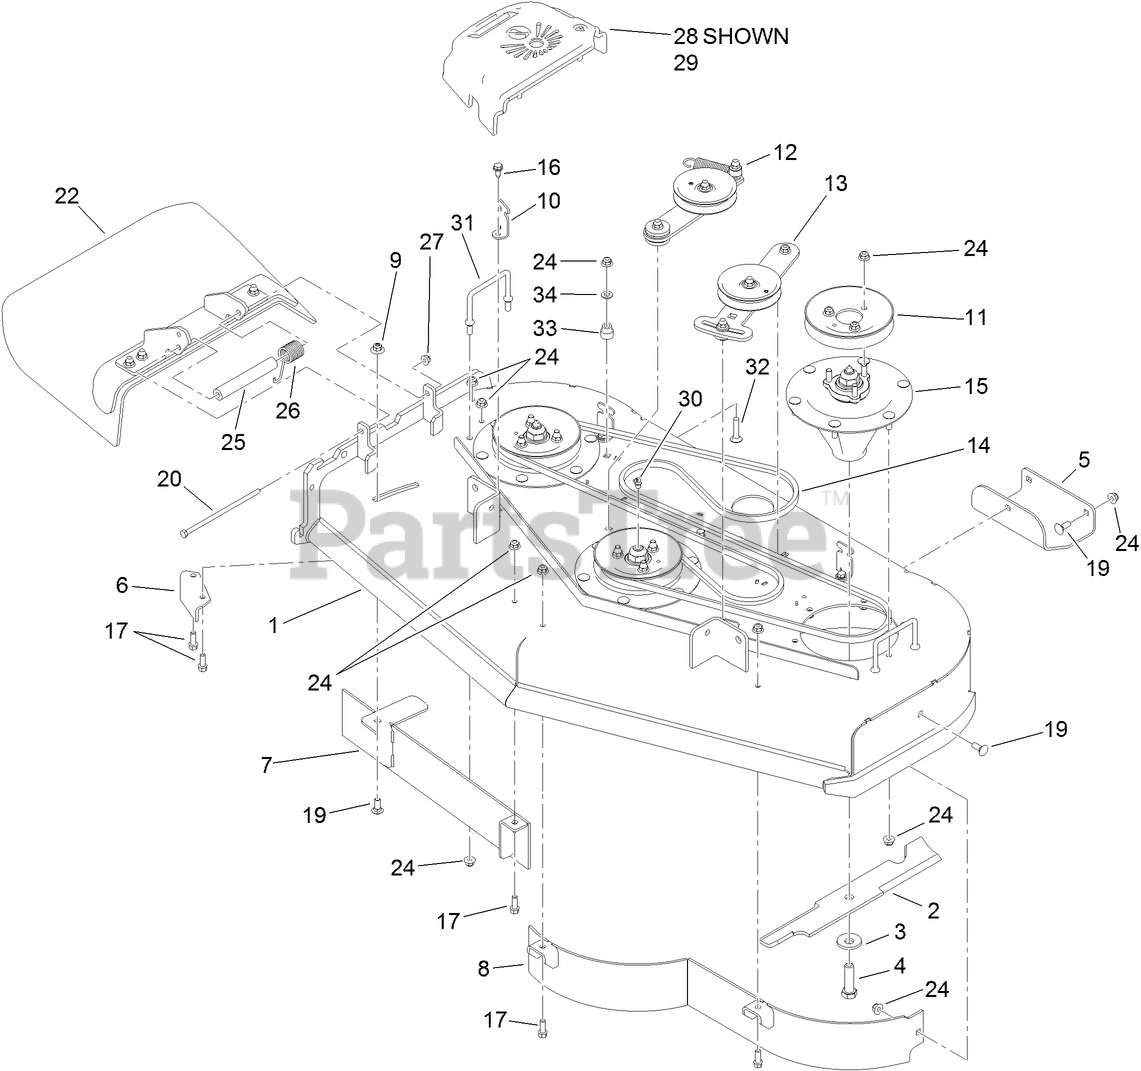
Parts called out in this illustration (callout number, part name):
1	DECK ASM
2	BLADE-16.5 INCH (HIGH FLOW)
3	Washer-Blade Bolt, Heavy
4	SCREW-BLADE
6	BAFFLE-DISCHARGE
8	48 INCH BAFFLE ASM
9	NUT-FLANGE, NI
10	BRACKET-COVER
11	PULLEY
12	IDLER ARM ASM
13	IDLER ADJUST ASM
14	BELT-V
15	SPINDLE ASM
16	SCREW-HWHTF
17	SCREW-HWH
19	BOLT-CARR
20	SCREW-HH
22	DEFLECTOR ASM
24	NUT-HF, NI
25	SPACER
26	SPRING-TORSION
27	NUT-HF, NI
28	COVER-BELT, RH
29	COVER-BELT
30	FITTING-GREASE
31	WIREFORM-COVER
32	SCREW-CARR
33	BUSHING-IDLER
34	WASHER-FLAT
